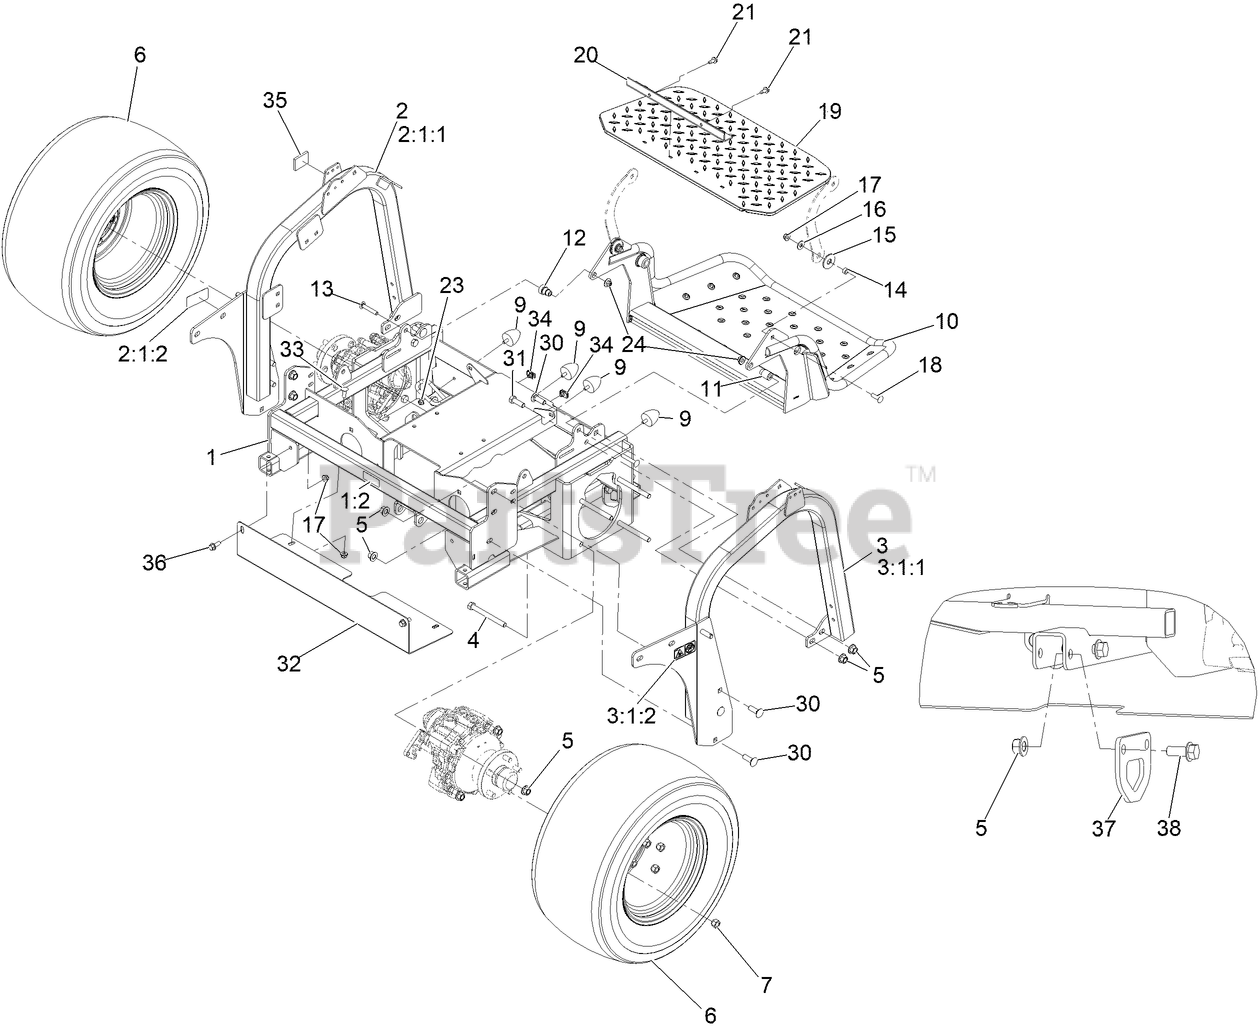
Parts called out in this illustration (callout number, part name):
1	Main Frame ASM W/Decal
1:2	DECAL-DANGER, BELT
2	RH FRAME ASM W/DECALS
2:1:1	Frame-RH
2:1:2	DECAL-HAZARD, PINCH
3	LH FRAME ASM W/DECALS
3:1:1	Frame-LH
3:1:2	DECAL-HAZARD, PINCH
4	SCREW-HH
5	Nut-Lock 1/2-13
6	WHEEL ASM, BLACK
7	NUT-LUG
9	BUMPER-RUBBER
10	Platform ASM-Red
11	BUSHING-FLANGED
12	BUSHING-FLANGED
13	BOLT-CARR, SHORT NECK
14	SPACER
15	WASHER-FRICTION, COMPOSIT
16	WASHER-FLAT
17	NUT-HF, NI
18	Bolt-Carriage 3/8-16 X 1 1/4
19	MAT-PLATFORM
20	CLAMP-SHIELD
21	Screw-HWH 5/16-18 X 3/4 Tf
23	NUT-HF, NI
24	Nut-Nyloc 3/8-16 Flg
30	Screw-CARR
31	SCREW-HH
32	Bracket-Shield, Belt
33	SCREW-CARR
34	NUT-CLIP, U
35	SEAL-FOAM
36	SCREW-HHF 3/8-16 X 1
37	PLATE-TIE DOWN
38	SCREW-HHF
